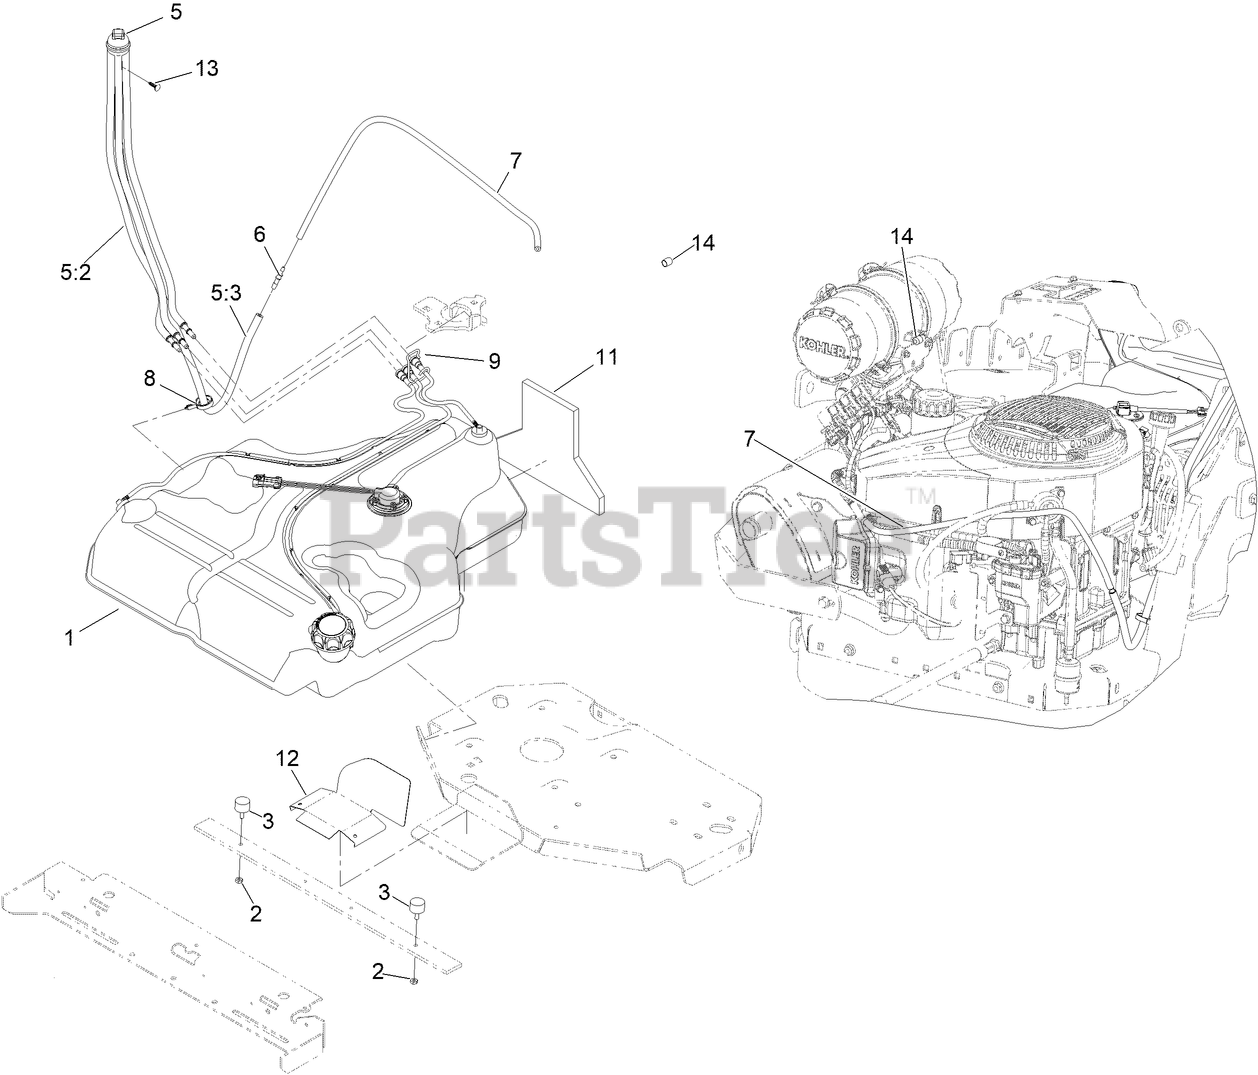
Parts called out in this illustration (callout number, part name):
1	FUEL TANK ASM
2	NUT-JAM
3	BUMPER
5	FUEL MANIFOLD VENT ASM
5:2	HOSE-FUEL
5:3	HOSE-FUEL
6	BARB-FUEL
7	HOSE-FUEL
8	CLAMP-HOSE
9	RETAINER-LINE, VAPOR
11	INSULATION-FOAM, FUEL TANK
12	GUARD-EXHAUST
13	PLUG-PLASTIC
14	PLUG-PORT
